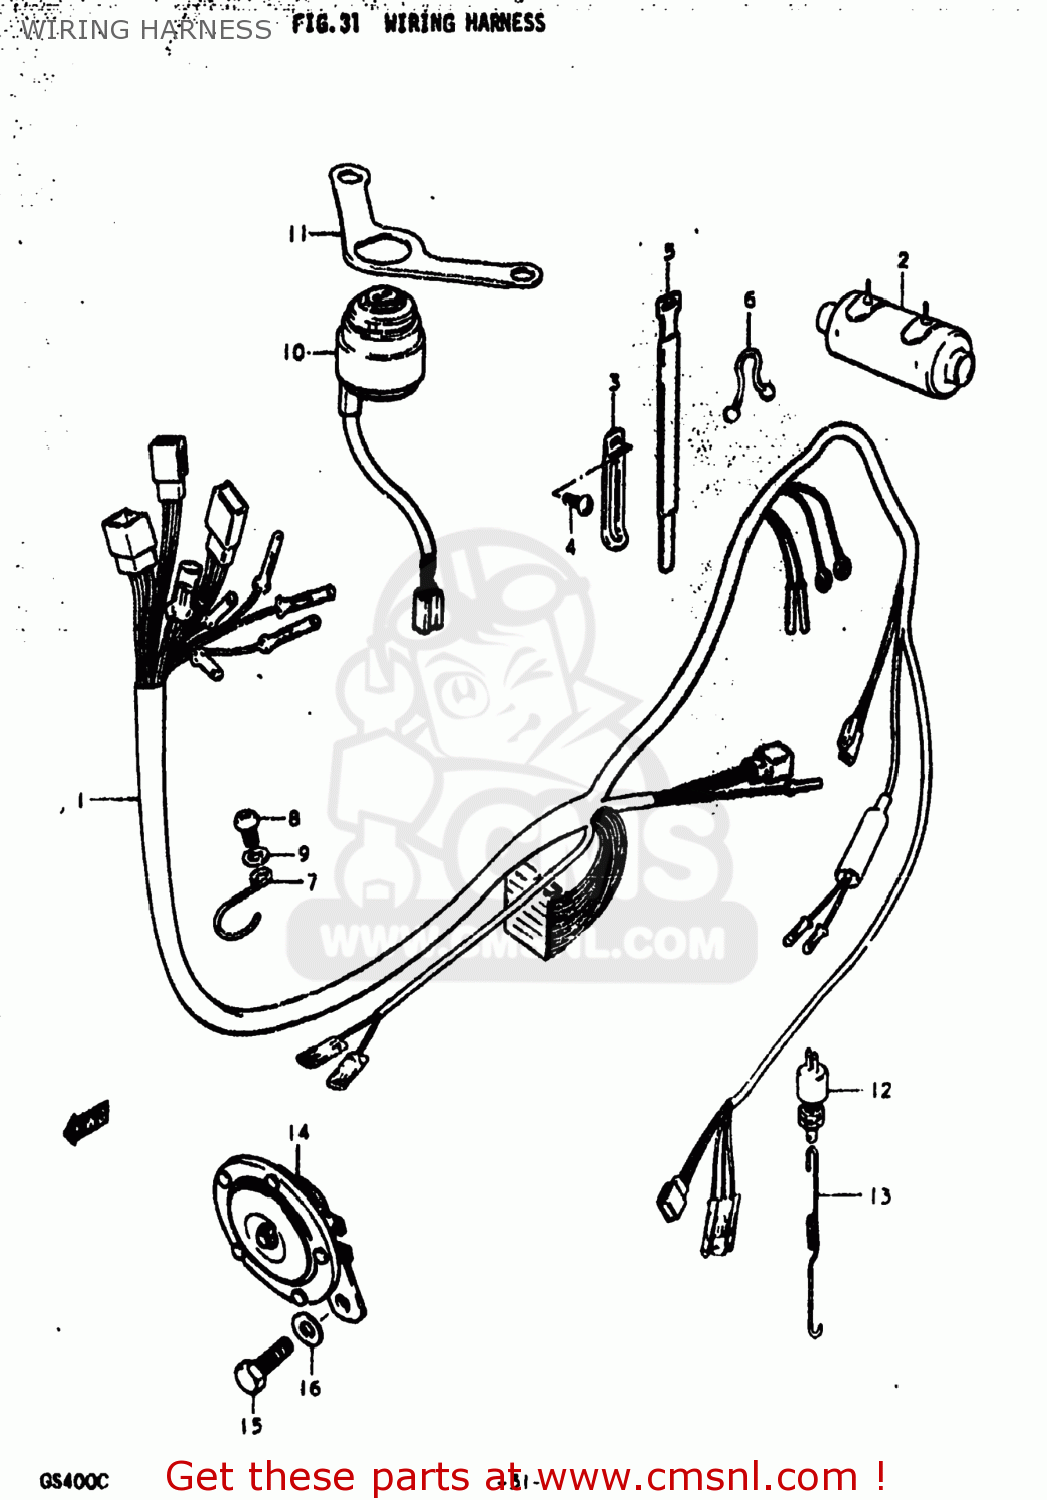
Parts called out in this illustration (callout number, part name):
1	HARNESS,WIRING
2	BOOT,WIRING HARNESS
3	CLAMP
4	SCREW
5	CLAMP
6	CLAMP
7	GUIDE,WIRING HARNESS
8	SCREW 6X12
9	WASHER 6MM
10	SWITCH ASSEMBLY,IGNITION
11	BRACKET,IGNITION SWITCH
12	SWITCH ASSY,BRAKE LAMP
13	SPRING
14	HORN ASSY
15	BOLT
16	WASHER
